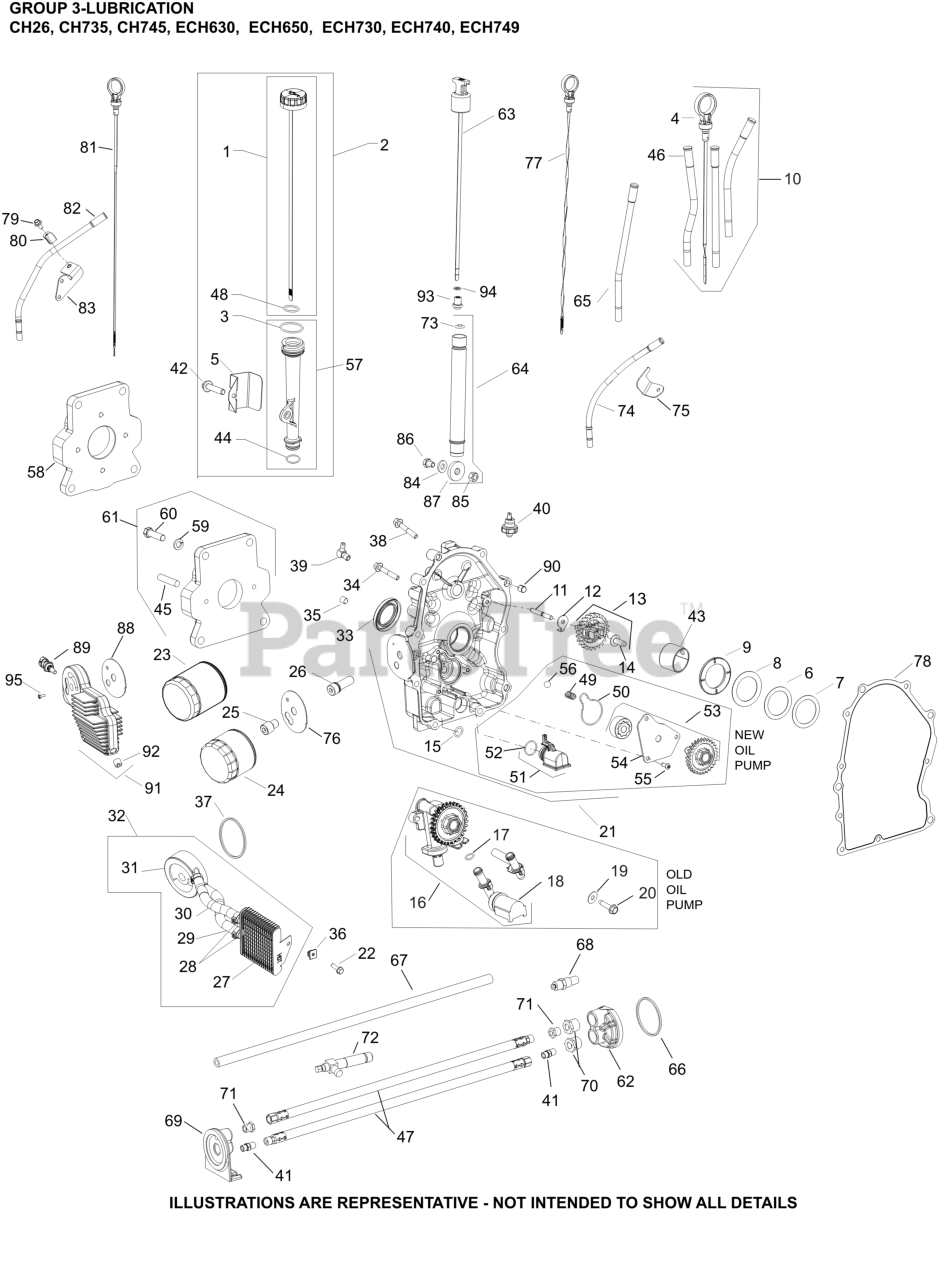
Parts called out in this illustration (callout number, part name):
21	KIT, CLOSURE PLATE ASSY
24	OIL FILTER
28	CLAMP, HOSE LOW PROFILE
30	KIT, HOSE 140MM
35	PLUG, CTSK PIPE 1/8"
36	NUT, PLASTIC - BLACK
37	O-RING, OIL COOLER
38	SCREW, FLG M8X1.25X45
38	SCREW, HEX FLANGE
40	SENSOR, OIL PSI
49	SPRING, COMPRESSION
50	SEAL, OIL PUMP COVER
51	PICK-UP ASSEMBLY, OIL
52	O-RING, OIL PICK-UP
53	PUMP ASSEMBLY, OIL
54	COVER, OIL PUMP
55	SCREW, BUTTON HEAD
56	PRESSURE RELIEF BALL
79	SCREW, FLG M6X1.0X12
80	CLIP, HOSE - DISCONTINUED
81	DIPSTICK, METAL
82	KIT, DIPSTICK TUBE
83	BRACKET, DIPSTICK TUBE SUPPORT
97	KIT, OIL FILTER NIPPLE
98	KIT, OIL COOLER
101	SCREW, HEX HEAD
NI	WASHER, FLAT
